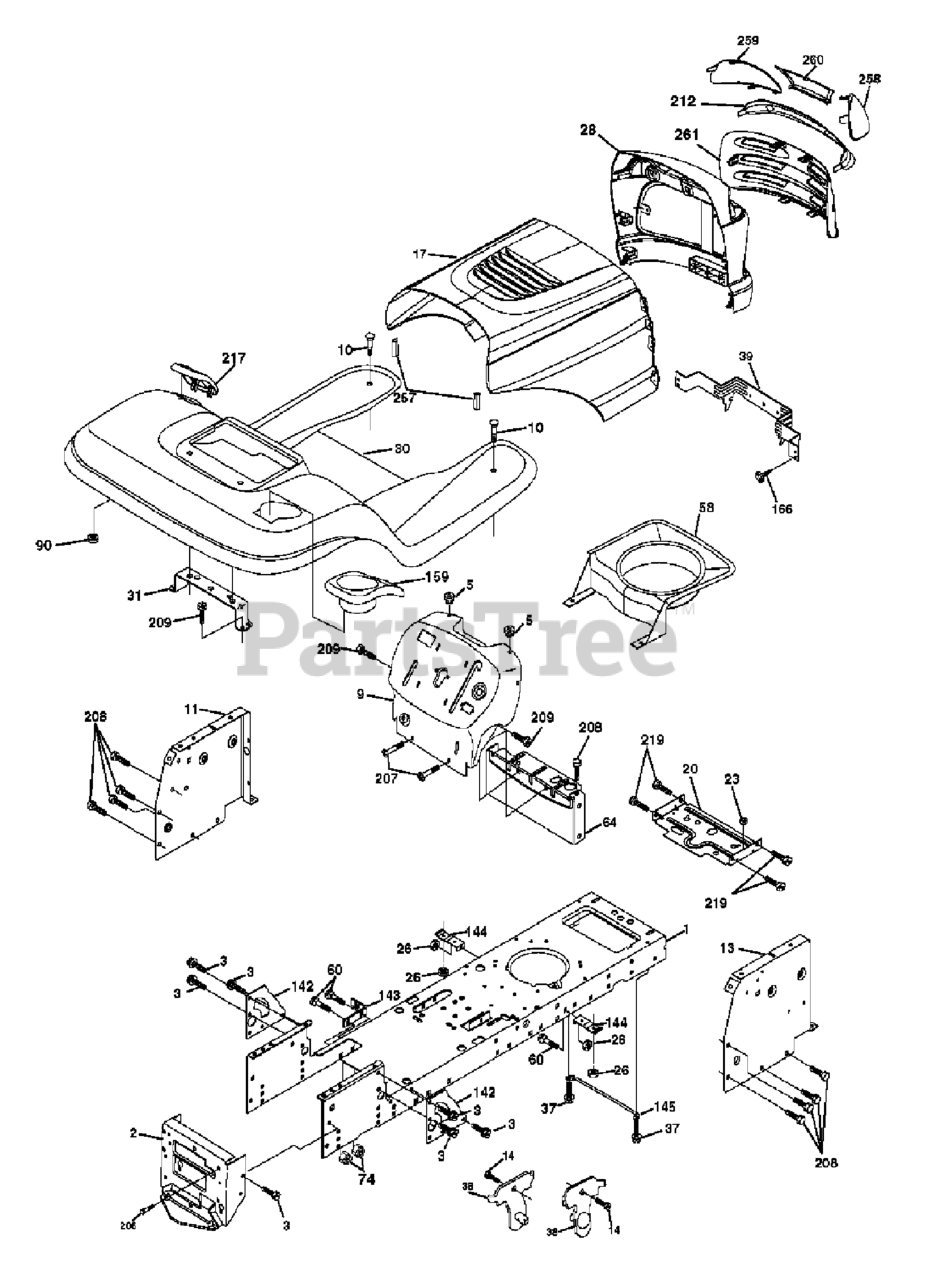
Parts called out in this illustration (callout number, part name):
1	CHASSIS STAMPING
2	DRAWBAR, 12GA
3	SCREW 3/8-16X3/4
5	BUMPER.RUBBER.HOOD
9	DASH SLKSCR
10	BOLT D
11	PANEL.DASH.LH.LTX
13	PANEL ASM, DASH RH
14	SCREW LT
17	HOOD
20	PLATE MTG.BATTERY/FUEL TANK
23	BUSHING.SNAP.NYL.BLK.
26	NUT
28	GRILL/LEN.ASM.DL.HUSQ
30	FENDER
31	BRACKET.SUPPORT.FENDER
37	Screw Thdrol 5/16-18 x 1/2
38	BRACKET.ASM.PIVOT.MOWER.REAR
39	BRACKET PIVOT LASER
60	Bolt RDHD SQNK 3/8-16 x 3/4
64	DASH LOWER
90	NUT.PUSH.3/16
142	PLATE REINFORCEMENT
143	BRACKET, SWAY BAR
144	BRKT, FOOT REST
145	ROD PIVOT CHASSIS/HOOD
159	GREY CUP HOLDER
166	SCREW
206	SHOULDER BOLT 5/16-18TT
207	SCREW, 5/16-18 X 1/2
208	SCREW 3/8-16X1/2
209	SCREW, 3/8-16X3/4
212	INSERT.LENS.REFLECTIVE
217	CONSOLE FUEL WINDOW
219	SCREW
257	BUMPER.HOOD.LARGE.1.75"
258	LENS LH
259	LENS LH
260	COVER.LENS.HUSQ.( HAVE GRAY)
261	INSERT GRILLE
